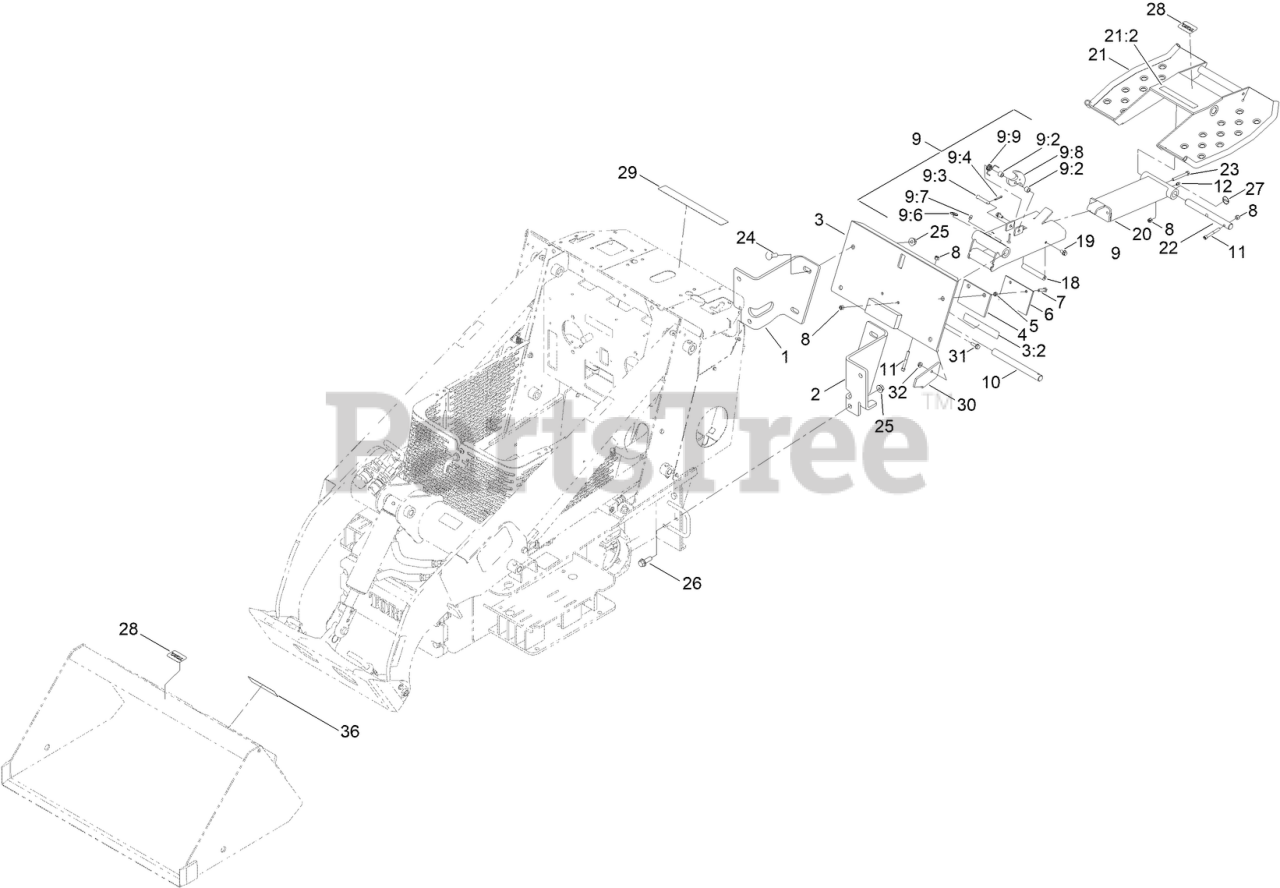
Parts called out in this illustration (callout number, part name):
1	PLATE-MTG, TX PLATFORM, RH
2	PLATE-MTG, TX PLATFORM-LH
3	SULKY MOUNTING PLATE ASM
3:2	DECAL-POINT, PINCH
4	PAD-RUBBER
5	SPACER
6	PLATE-PUSH
7	SCREW-HH
8	NUT-LOCK, NI
9	LINKAGE ASM
9:2	SPACER
9:3	PIN-CLEVIS
9:4	PIN-COTTER
9:6	DECAL-GREASE
9:7	FITTING-GREASE
9:8	LATCH-PLATFORM
9:9	SPRING-TORSION, RH
10	PIN-UPPER
11	SCREW-HSH
12	FITTING-GREASE
18	ROD-CLAMP
19	SCREW-HHF
20	SLIDE ASM, WELDED
21	PLATFORM ASM
21:2	DECAL-POINT, PINCH
22	PIN-LOWER V
23	SCREW-HH
24	SCREW-CARR
25	NUT-HHF
26	SCREW-HHF
27	DECAL-GREASE
28	DECAL
29	DECAL-WARNING/INSTRUCTIONAL
30	PLATE-BUMPER
31	SCREW-HHF
32	NUT-HF
36	DECAL - CAPACITY
